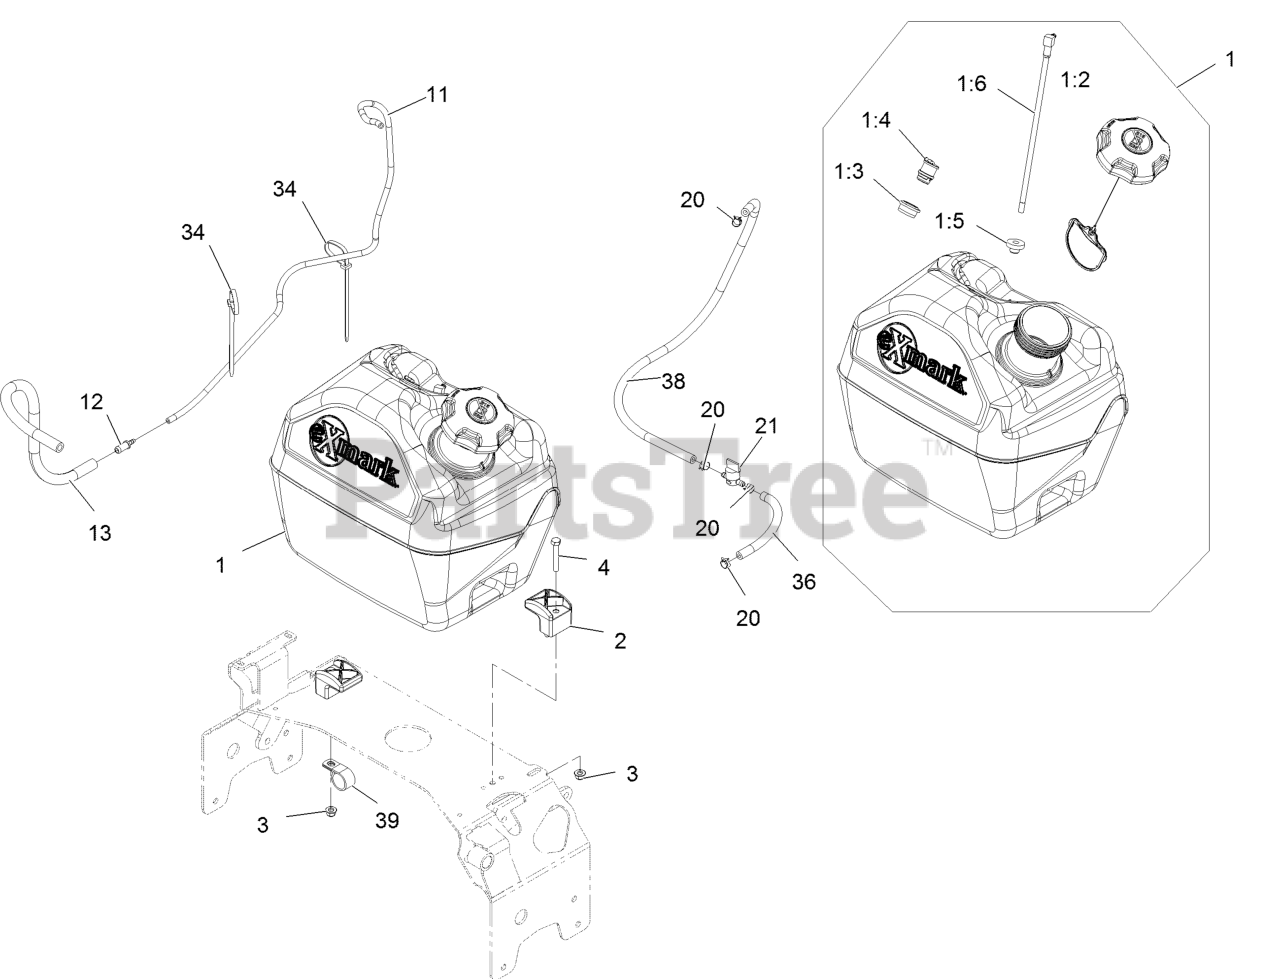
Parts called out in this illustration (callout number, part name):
1	ASM, Fuel Tank 5 Gal
1:2	Cap-Fuel, Ratcheting
1:3	Grommet
1:4	Valve-Vent, Fuel
1:5	Bushing
1:6	Fitting-Fuel (W/Line And Screen)
3	Nut-Nyloc 5/16-18 Flg
4	Screw-HH 5/16-18 X 2
11	Hose, Emissions
12	Fitting-Straight
13	Hose-Fuel
20	Clamp-Hose
21	Valve-Fuel
34	Tie-Cable 7 15/16 (Large)
36	Hose-Fuel
38	Hose-Fuel Line 32"
39	Clip-Loom
